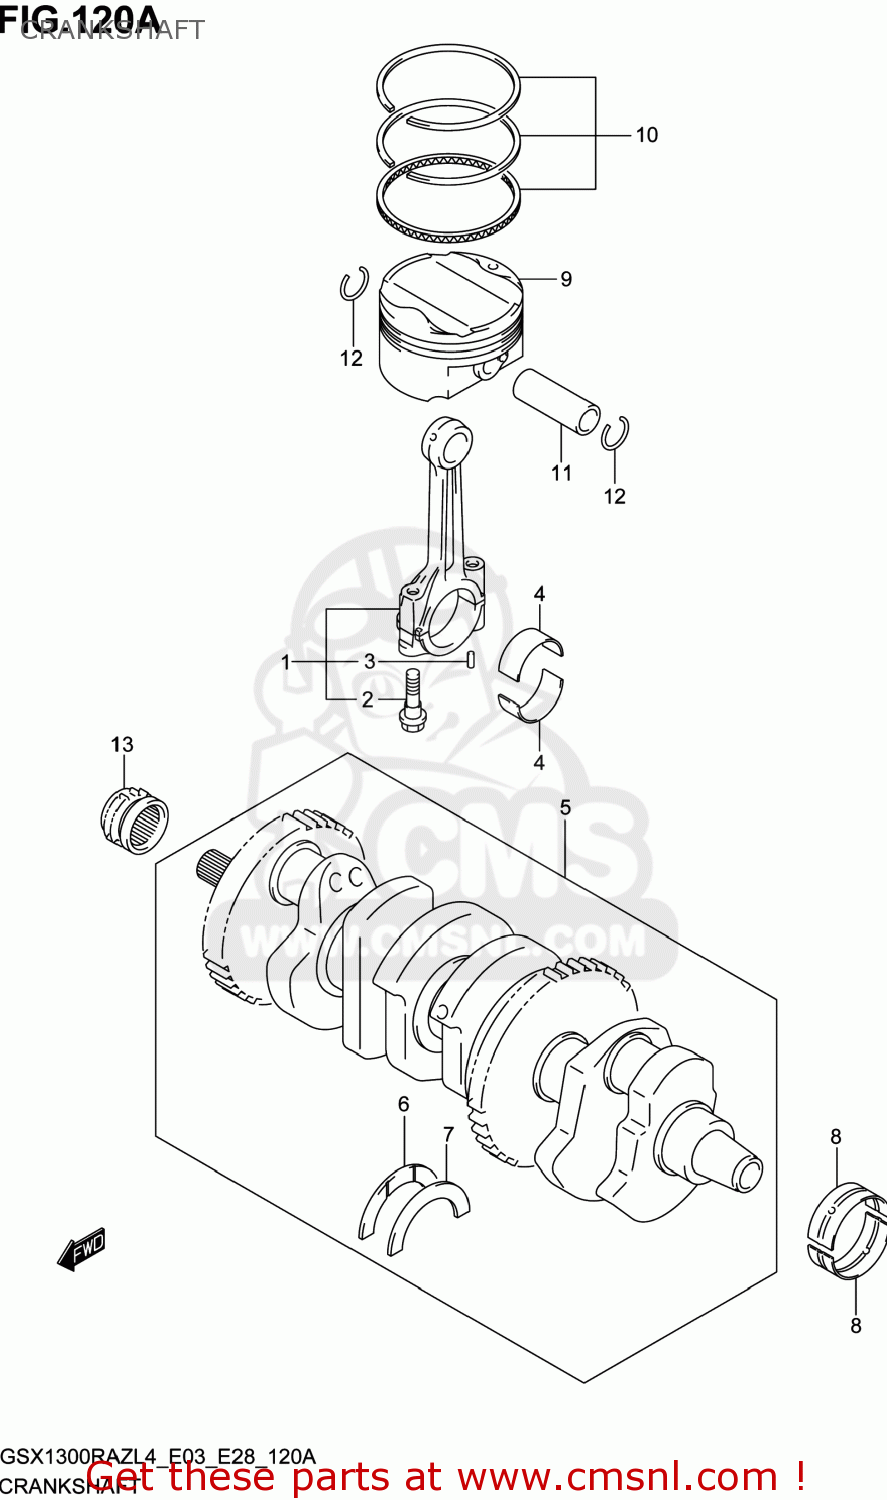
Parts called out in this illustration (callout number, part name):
1	CONNECTING ROD ASSY
2	BOLT,CONNECTING ROD
3	PIN
4	BEARING,CRANK PIN
5	CRANKSHAFT SET
6	BEARING,CRANK THRUST,L
7	BEARING,CRANK THRUST,L
8	BEARING,CRANKSHAFT
9	PISTON
10	RING SET,PISTON
11	PIN,PISTON
12	CIRCLIP
13	SPROCKET,CAM CHAIN DRIVE
